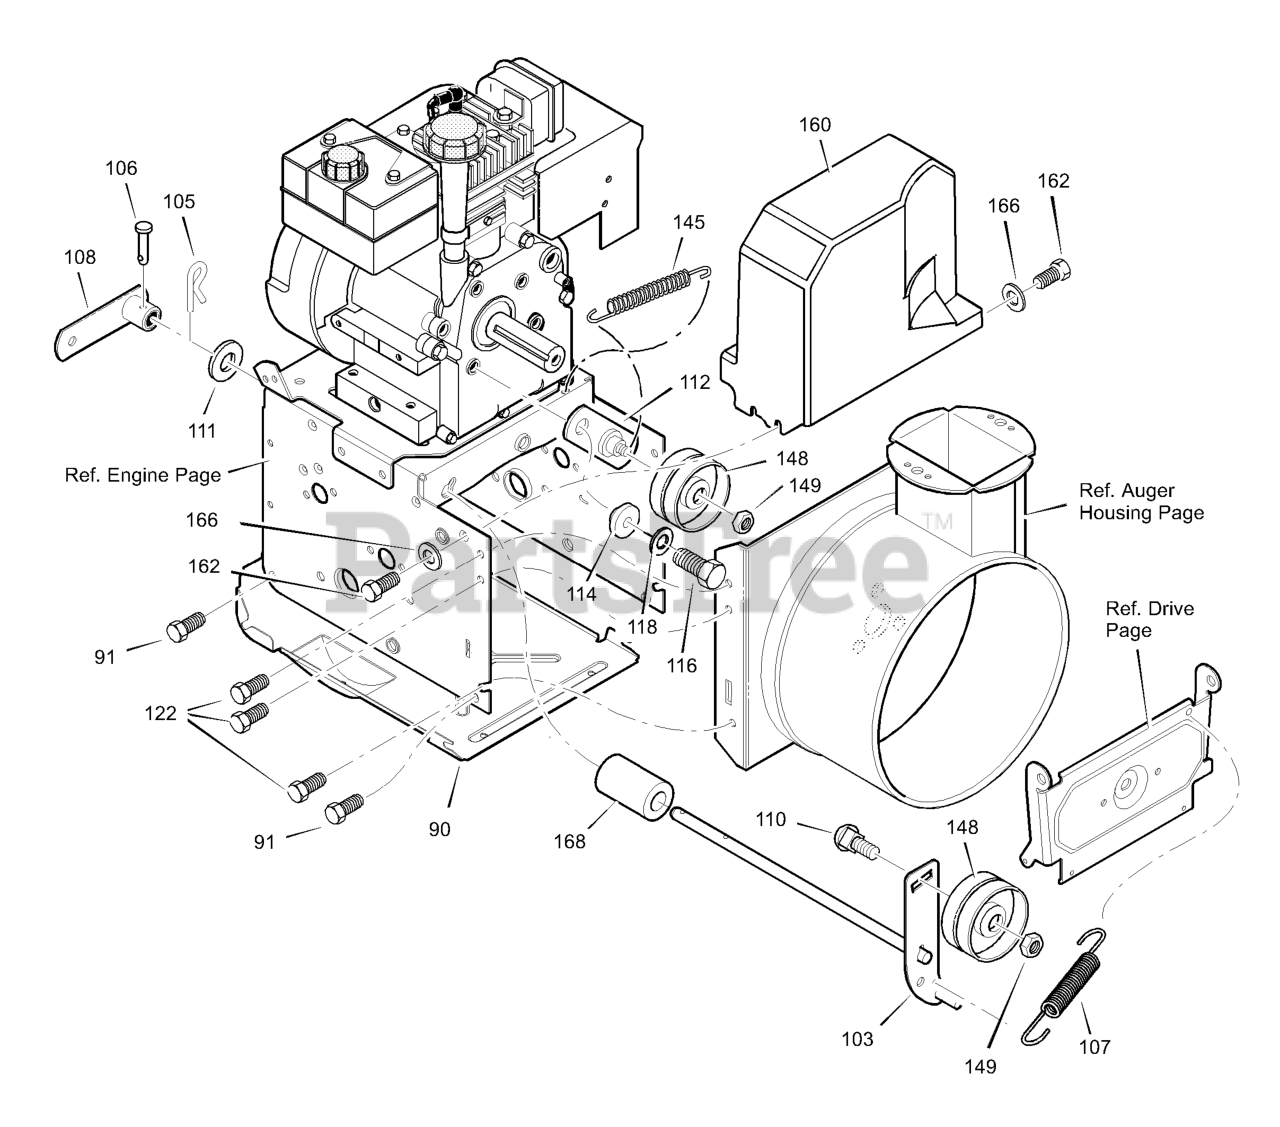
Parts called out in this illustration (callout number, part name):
90	COVER, BOTTOM
91	SCREW, 1/4-20X .63
103	IDLER ASSEMBLY, AUGER
105	PIN, HAIR .38DIAX1.64LG
106	PIN, CLEVIS 3/16" DIA
107	SPRING, TENSION
108	ASSY., SPRING ATTACH
110	BOLT, 3/8-16X1.25 CARR.
111	WASHER, FLAT
112	BRACKET ASSEMBLY, IDLER
114	BUSHING, IDLER BRACKET
116	SCREW 5/16-24 X 1.00
118	WASHER, SPLIT
122	SCREW, TAP 5/16-18 X .50
145	SPRING, IDLER TRACTION DRIVE
148	PULLEY, IDLER
149	NUT, JAM 3/8-16
160	COVER, BELT
162	SCREW, TAP 1/4-20 X .63
166	WASHER, FLAT
168	SPACER, AUGER BRACKET
